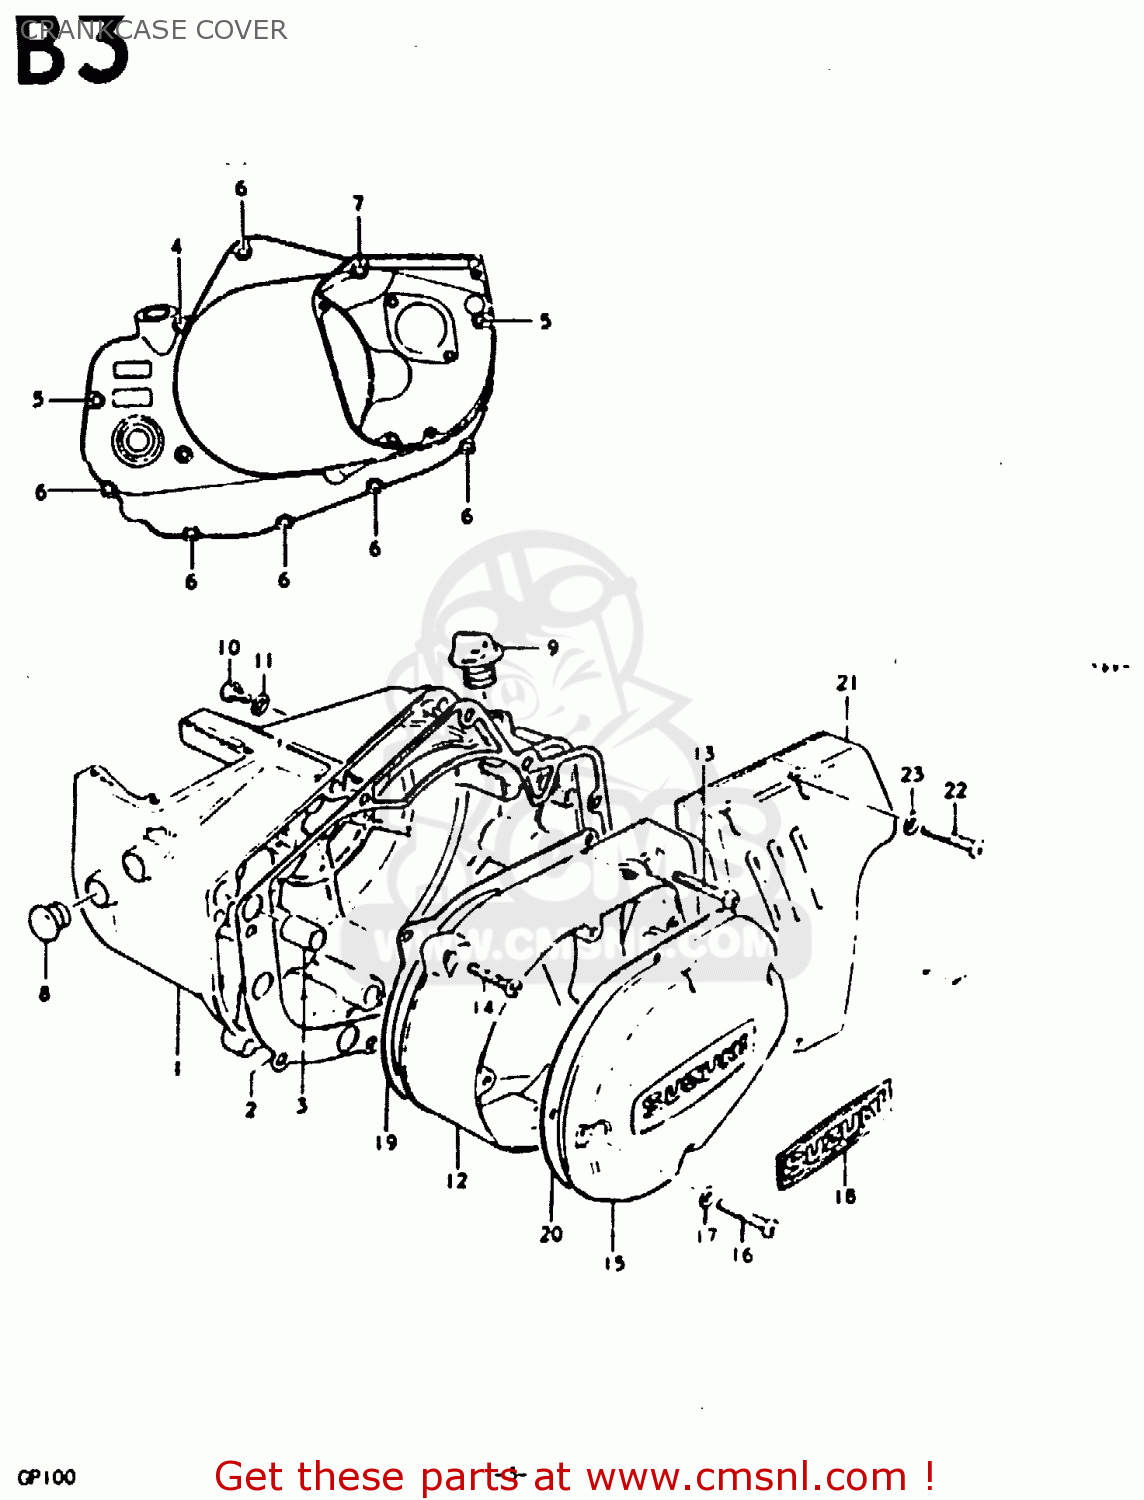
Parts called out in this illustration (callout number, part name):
1	COVER, CLUTCH
2	GASKET, CLUTCH COVER (MCA)
3	PIN
4	SCREW
5	SCREW
6	SCREW
7	SCREW
8	Plug
9	PLUG,OIL FILTER
10	SCREW(6X10)
11	GASKET(6.2X11X1) (NAS)
12	COVER, MAGNETO
13	SCREW (6X35)
14	SCREW
15	CAP, MAGNETO INSPECTION
16	SCREW
17	WASHER
18	EMBLEM,MAG INSPECTION CAP
19	GASKET, MAGNETO COVER
20	GASKET,MAGNETO INSPECTION CAP (NAS)
21	COVER, ENGINE SPROCKET
22	SCREW (6X35)
23	WASHER
